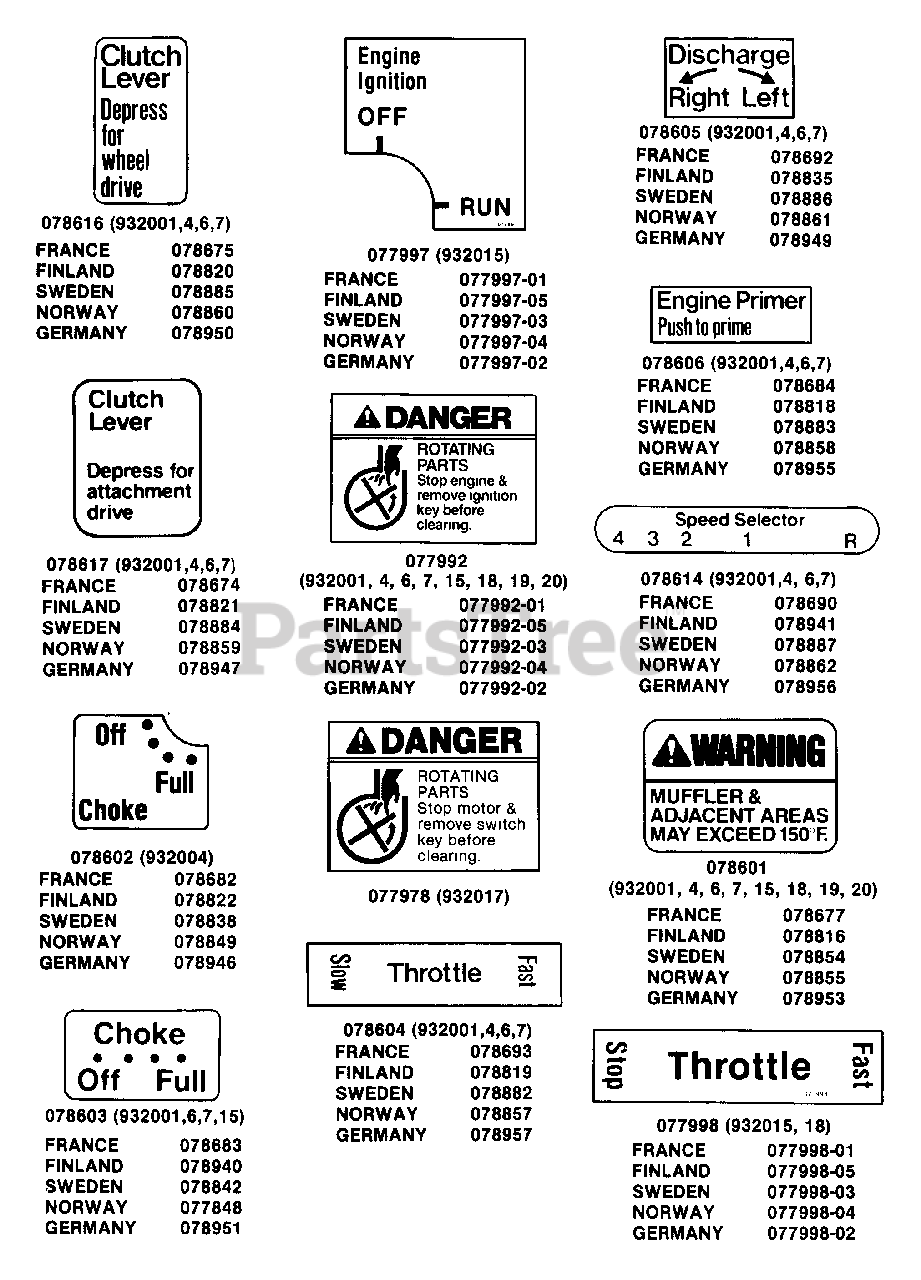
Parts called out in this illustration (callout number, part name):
1	DANGER DECAL ROTATING PARTS
2	DANGER DECAL ROTATING PARTS
3	SWITCH DECAL
4	THROTTLE DECAL
5	WARNING DECAL
6	CHOKE DECAL
7	CHOKE DECAL
8	THROTTLE DECAL
9	CHUTE CRANK DECAL
10	SPEED SELECTOR DECAL
11	CLUTCH DECAL
12	CLUTCH DECAL
